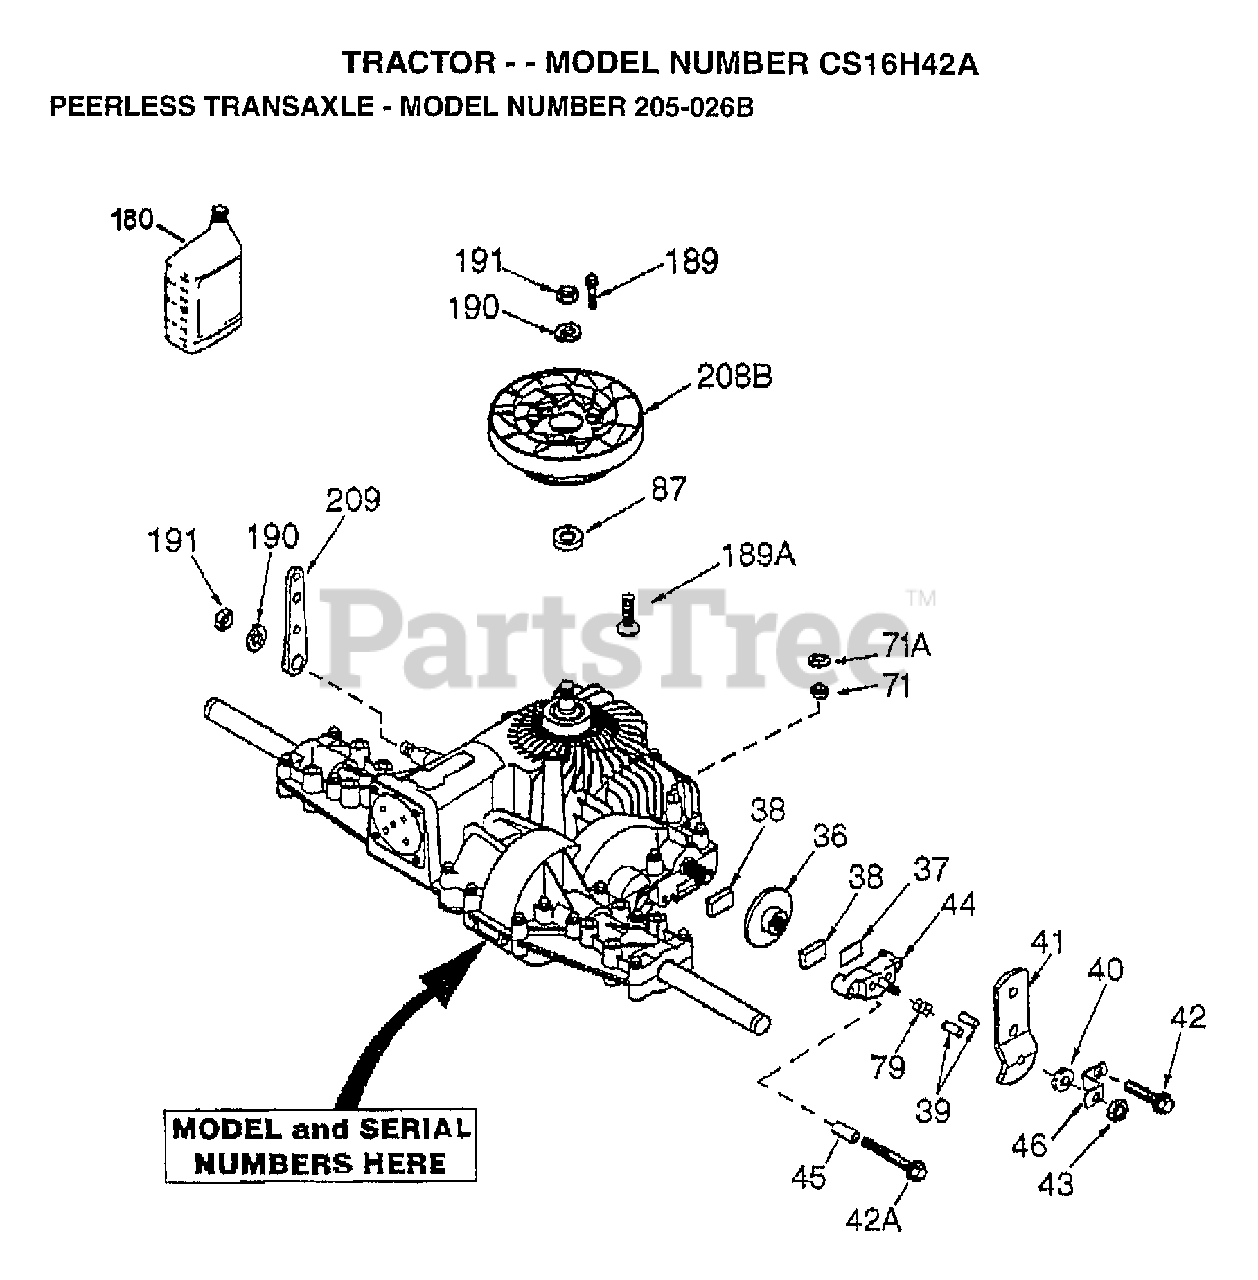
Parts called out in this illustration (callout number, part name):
37	PLATE BRAKE PAD
41	BRAKE LEVER
42	SCREW, 1/4-20 X 1-1/4
42A	SCREW, 1/4-20 X 2-1/4
43	LOCKNUT 5/16-24
44	HOLDER BRAKE PAD
46	BRAKE LEVER BRACKET
71	SEAL SQUARE CUT
180	GEAR OIL 80W90
189	DRIVE SCREW
208B	FAN/COUPLING
209	CONTROL LEVER
